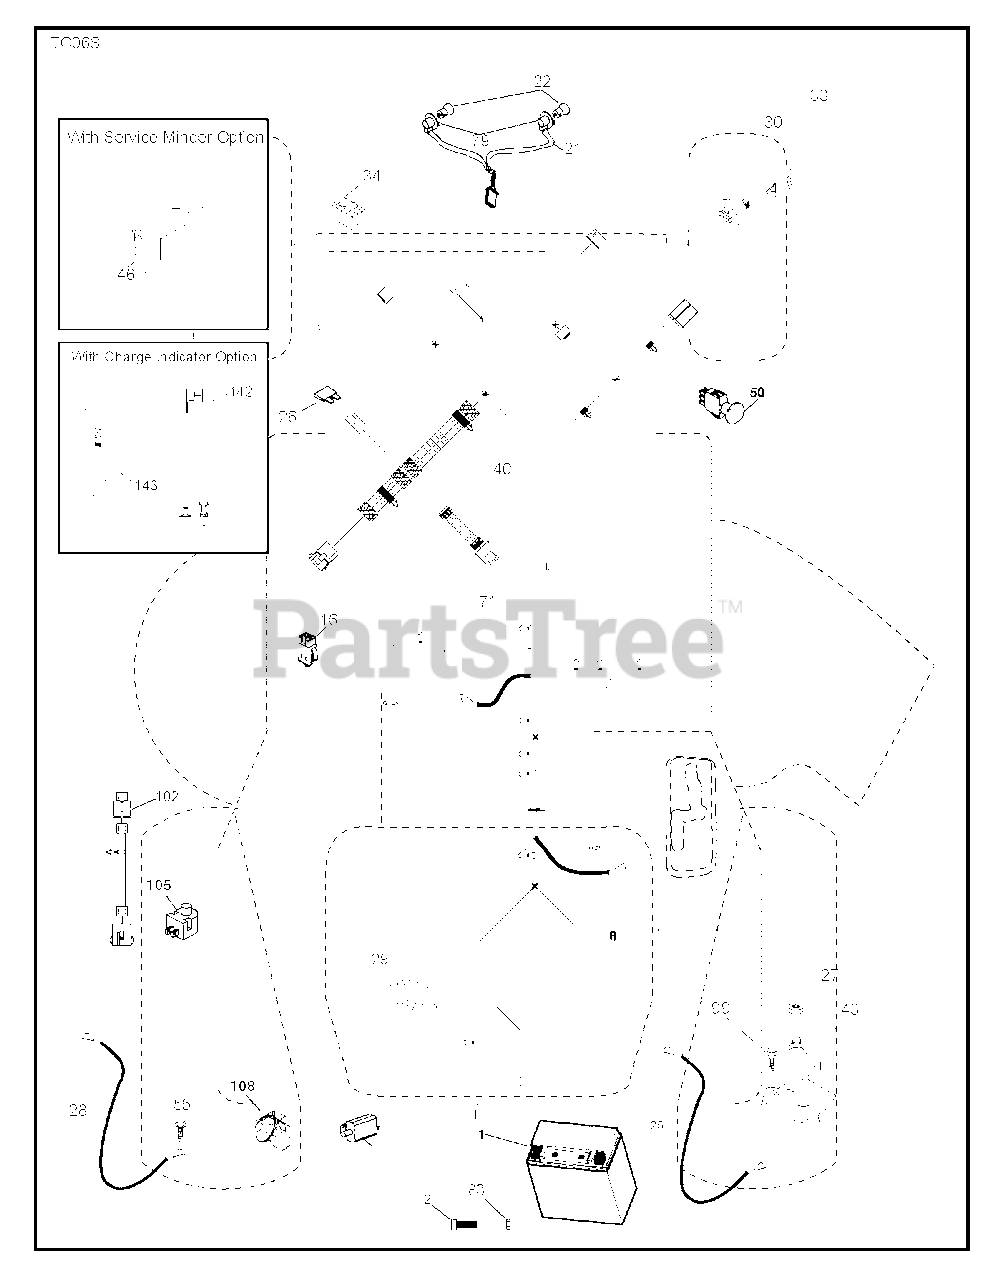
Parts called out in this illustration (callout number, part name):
1	BATTERY BATTERY 14AH 12V LEOC
2	SCREW.HEX.HEAD.CAP.M6 X1.12W
16	SWITCH INTERLOOK PUSH-IN
21	HARNESS.LIGHT W/4152J BULBS
25	CABLE.RED.8AWG.TCRD.GEN1
26	FUSE 20AMP
27	NUT
28	CABLE.BLACK.8AWG.TCRD.GEN1
29	SWITCH.SEAT.DELTA.OPC.
30	SWITCH.IGN.DELTA.W.LGH.ROS
33	KEY.CHAIN.BLISTER.PACK.GEN.INT
40	HARNESS.CHASS.CRD.TEX.RDY.STRT
43	SOLENOID.W/BRASS.PLUNGER
46	GUAGE.SRVCMNDR.HRMTR.
50	RB PTO.SWITCH.8 TERMINAL.BLACK
55	SCREW 5/16"
71	HARNESS.CHASS.CRD.TEX.RDY.STRT
79	BULB HOLDER ASM.
83	NUT NUT SQUARE
99	SCREW
102	HARNESS ASSY
105	REVERSE SWITCH
107	.WITCH.FULL BAGGER.INDICATOR
108	SWITCH.SNAPMOUNT.NC
142	CHARGE.PORT.PIGTAIL HARNESS
143	CHARGE.PORT
